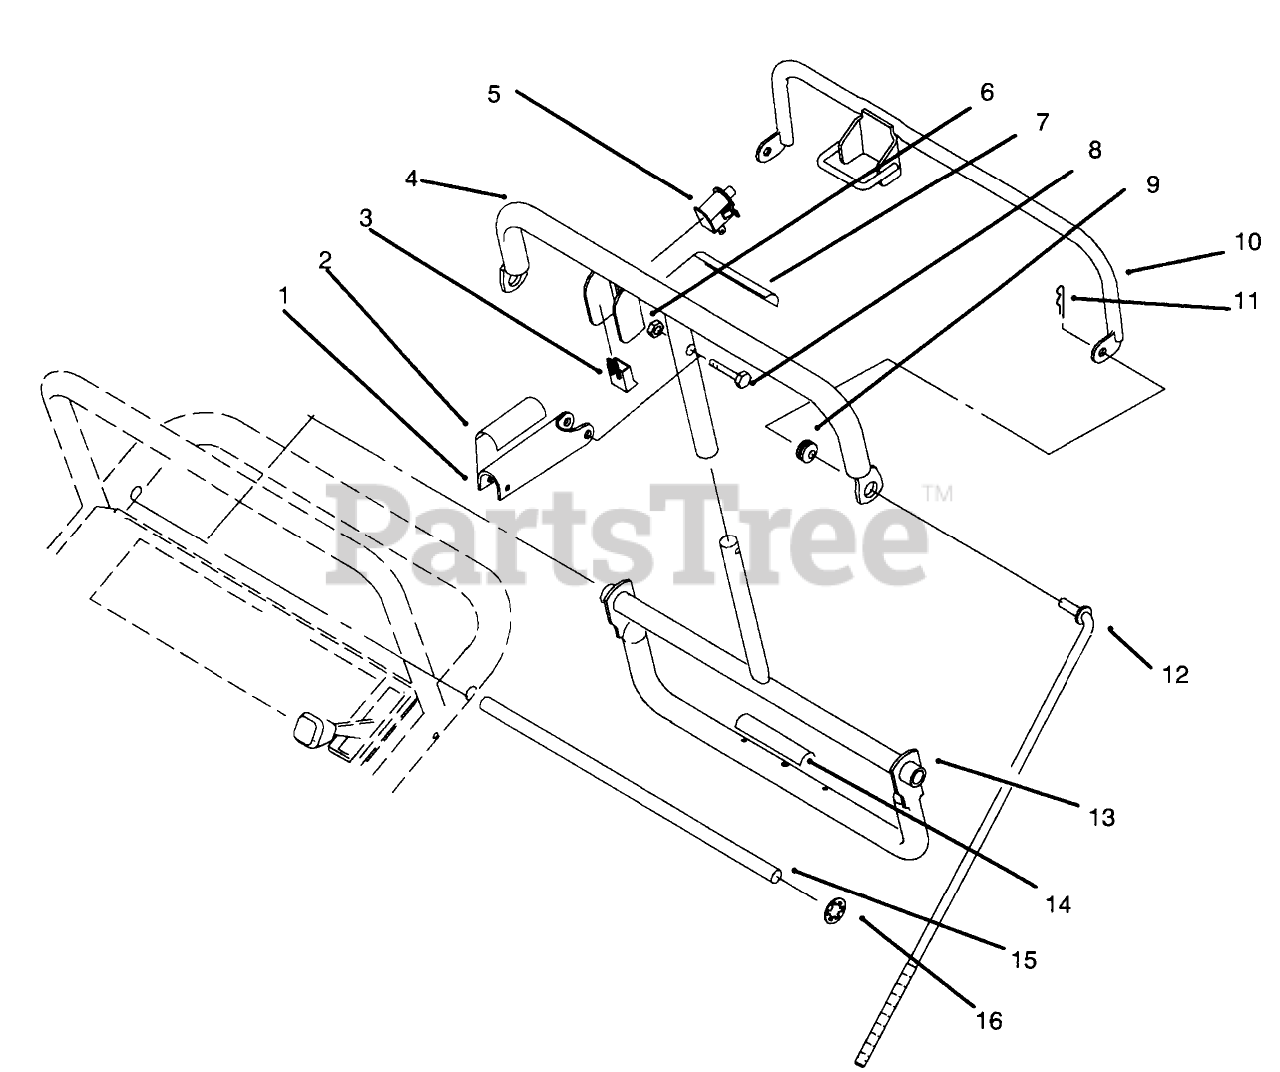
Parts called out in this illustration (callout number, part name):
1	Lever-Parking Brake
2	DECAL-LEVER, PARKING
3	CONNECTOR-BODY
4	Bar
5	SWITCH-BAIL
6	NUT-LOCK, NI
7	DECAL-BAR, CONTROL
8	SCREW-SHH
9	GROMMET-RUBBER
10	Bail
11	PIN-COTTER
12	ROD-CONTROL
13	Control Pivot
14	DECAL-REVERSE
15	PIVOT ROD
16	NUT-PUSH-ON, CIRCULAR
